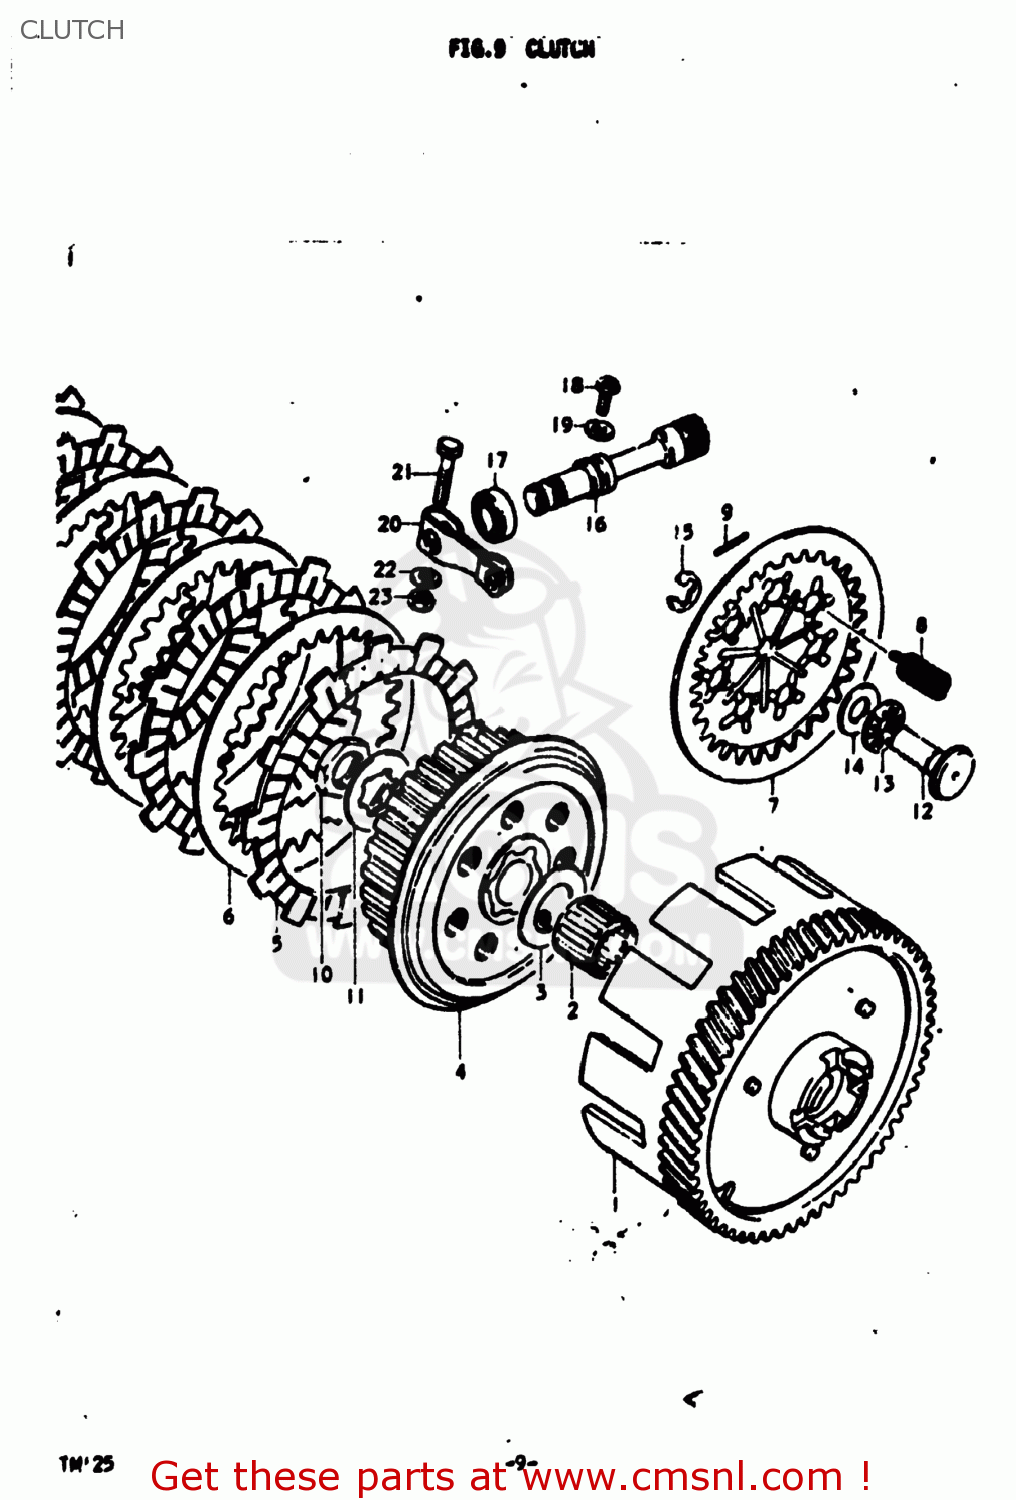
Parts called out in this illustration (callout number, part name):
1	GEAR ASSEMBLY,PRIMARY DRIVE
2	BEARING
3	WASHER
4	HUB,CLUTCH SLEEVE
5	PLATE,CLUTCH DRIVE
6	PLATE,CLUTCH DRIVEN (NAS)
7	PLATE,CLUTCH PRESSURE
8	SPRING
9	PIN(2.5X19.8)
10	NUT
11	WASHER,LOCK
12	RACK,CLUTCH RELEASE
13	BEARING(10X22X2.8)
14	WASHER
15	E RING 8MM
16	PINION,CLUTCH RELEASE
17	OIL SEAL
18	BOLT(6X12)
19	WASHER
20	ARM,CLUTCH RELEASE
21	BOLT
22	WASHER
23	NUT
